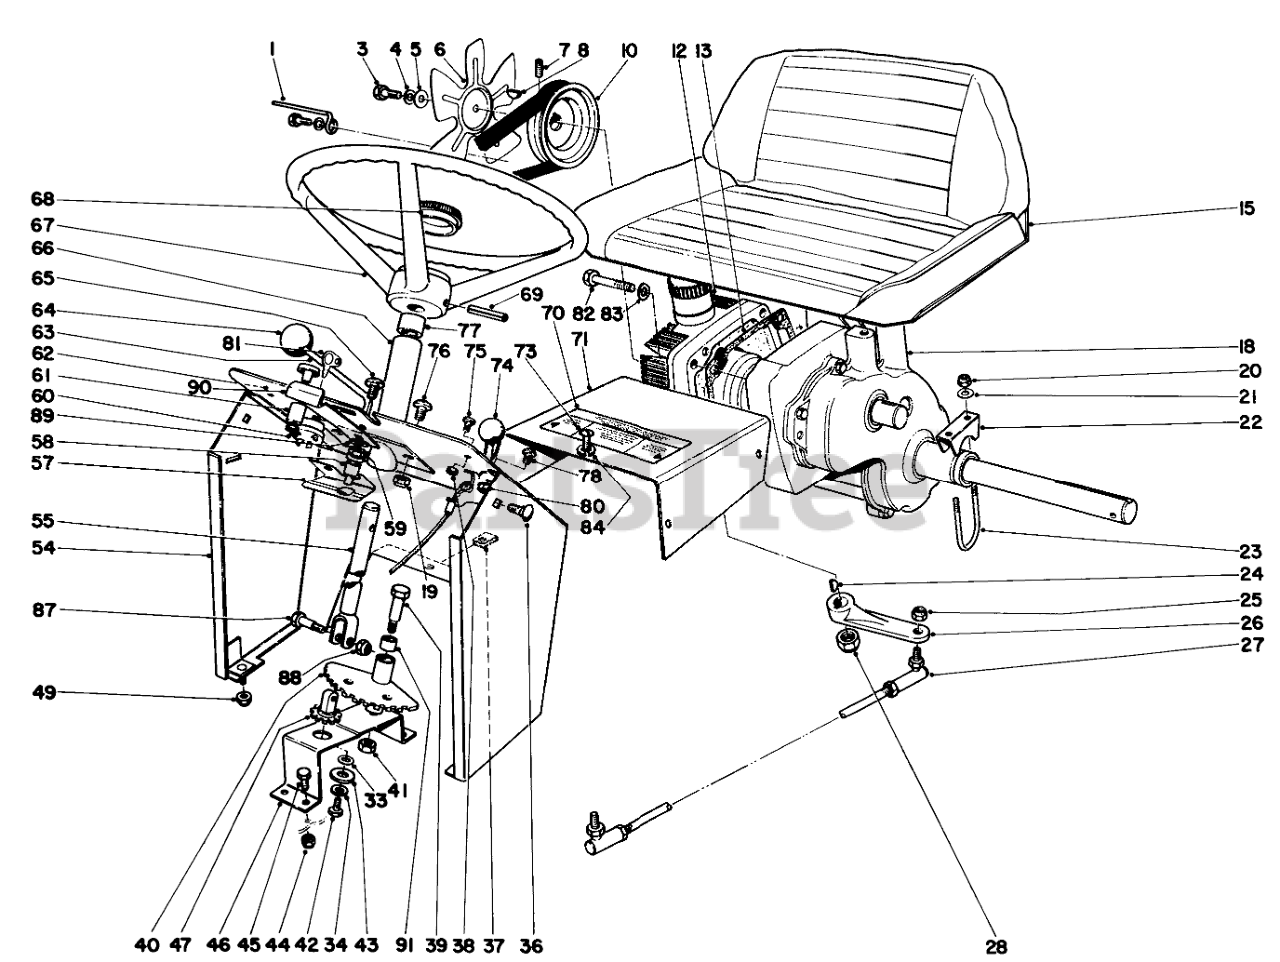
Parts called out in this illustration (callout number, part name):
1	Belt Guide
3	SCREW-HH
4	WASHER-LOCK
5	WASHER-FLAT
7	SCREW-SET, HSH
8	KEY-WOODRUFF
10	Pulley
12	Hydrostatic Transmission
13	Gasket
18	Transaxle
19	Nut
20	Locknut
21	WASHER-FLAT
22	Axle Bracket
23	U-Bolt
24	KEY-WOODRUFF
25	Locknut
26	Lever Hydrostatic
27	Control Rod Transmission
33	Spacer
34	WASHER-LOCK
36	BOLT-CARR
37	SPEED NUT
38	NUT-HEX
39	Shoulder Bolt
40	Gear Steering
41	Nut
42	SCREW-HH
43	Washer
44	Nut
45	SCREW-HH
46	Bracket
47	Pinion Steering
49	Nut
55	Steering Shaft
57	Spring Detent
58	Bushing
60	STARTER SWITCH
61	Light Switch
62	Decal Dash
63	Handle Hydro Control
65	Carriage Bolt
66	Steering Tube (Incl. Ref. #77)
67	Steering Wheel
68	Steering Wheel Cap
69	Roll Pin
70	Decal
71	Tunnel
73	SCREW
74	Throttle Control
76	Truss Head Screw
77	Bushing
80	NUT-HEX
81	Key
82	SCREW-HH
83	WASHER-LOCK
84	WASHER-LOCK
87	Screw Shoulder
88	NUT-HEX
89	WASHER-FLAT
90	Hood Latch
91	BUSHING
